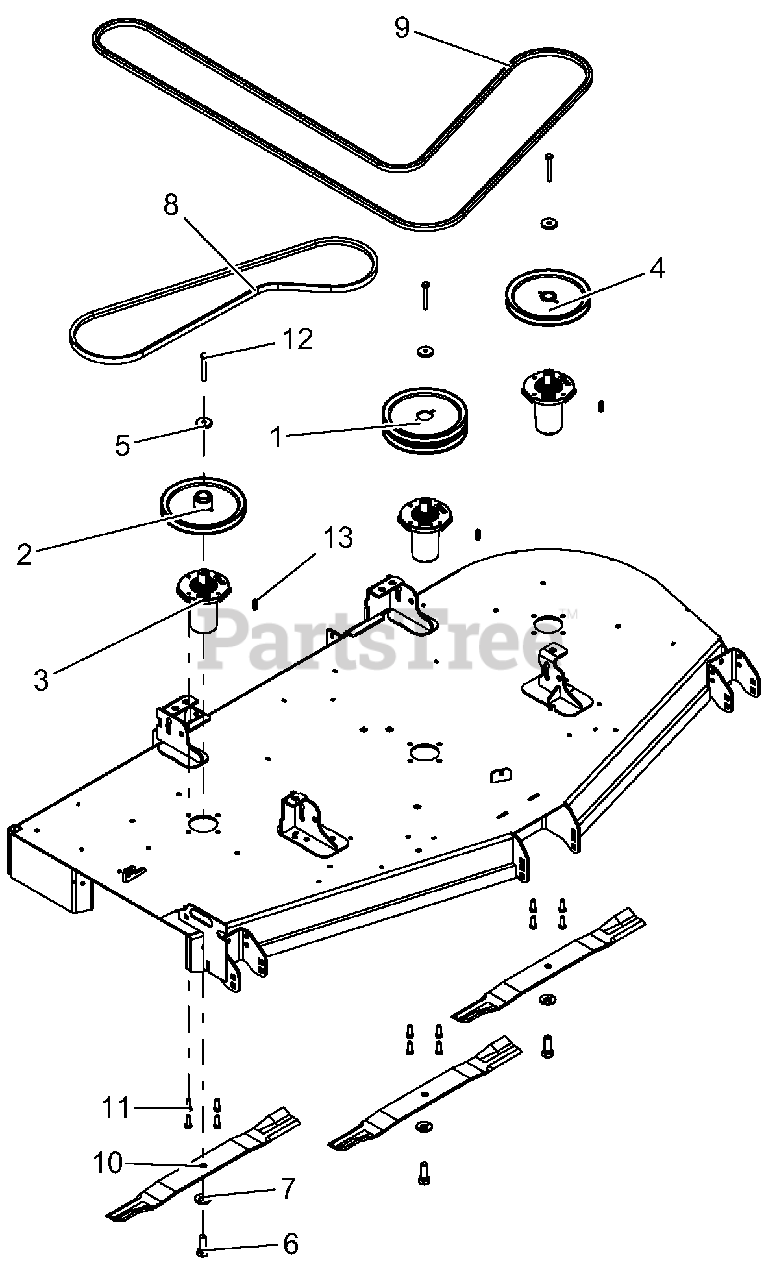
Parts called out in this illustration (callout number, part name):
1	SHEAVE-DOUBLE 1.00"ID X 8.25"OD-BLACK
2	SHEAVE, SINGLE 1.00" ID X 8.25" OD-BLACK
3	SERVICE, ASM SPINDLE- DUCTILE
4	SHEAVE-SINGLE 1.00" X 8.25" OD-BLACK
5	RETAINER, SHEAVE SPINDLE
6	BLT, HEX .62-18X1.75 GR8 YWZC
7	WSHR, BLVL .63X1.625X.14
8	V-BELT, B-COGGED
9	HEX BELT, BB-WRAPED
10	BLADE, MOWER 72" (24.5" LG)
11	BLT-HEX .38-16X1.00 GR5 YWZC EP30
12	BLT-HEX .38-16X2.75 GR8 YWZC
13	KEY-SQ .250X.250X1.00 RC 40-50
